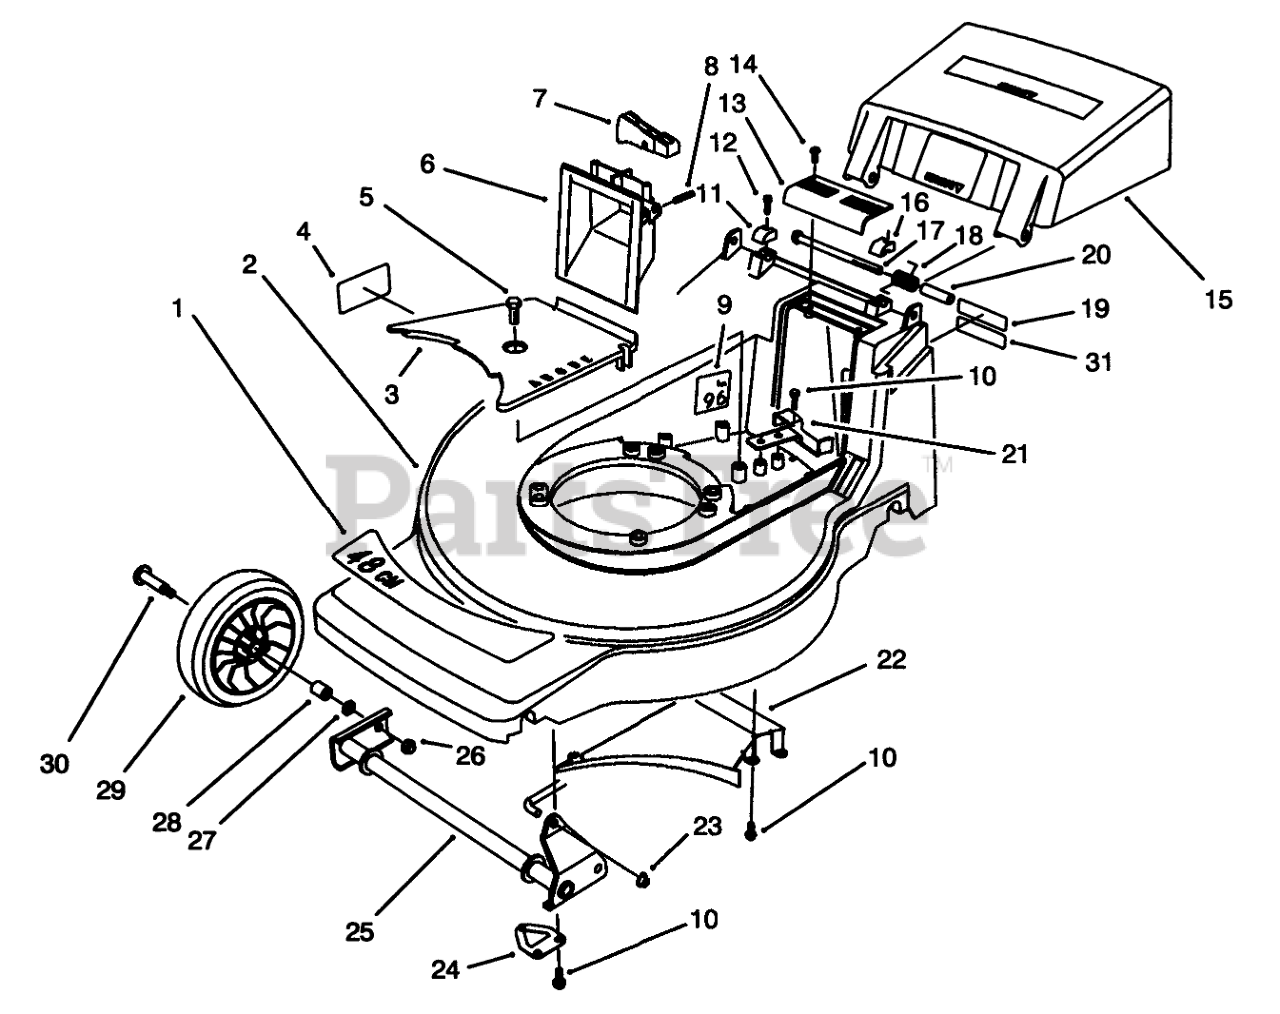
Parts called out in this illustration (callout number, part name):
1	DECAL - DECK 48 CM
2	Housing-48cm (Incl. Ref. #4)
3	BELT COVER
4	Decal Danger
5	SCREW-HWHTF
6	GRIP - LOWER
7	TRIGGER - HOC
8	PIN-SPIRAL
9	Decal-Noise Rating
10	SCREW-HWH
11	CAP-HINGE BOLT, RH
12	SCREW-HSH
13	GRIP-UPPER
14	SCREW-PPH, PLASTITE
15	Door Discharge
16	CAP-HINGE BOLT, LH
17	SCREW-HH
18	SPRING-DOOR
19	DECAL FRENCH REGUL.
20	SPACER-DOOR
21	REAR BELT GUIDE
22	Ramp-Discharge
23	NUT-PUSH
24	SHAFT RETAINER ASM
25	FRONT PIVOT WA
26	NUT-HEX
27	WASHER
28	BUSHING
29	Wheel & Tire Assembly (Incl. Ref. #28)
30	BOLT-WHEEL
31	Decal-Power Rating
